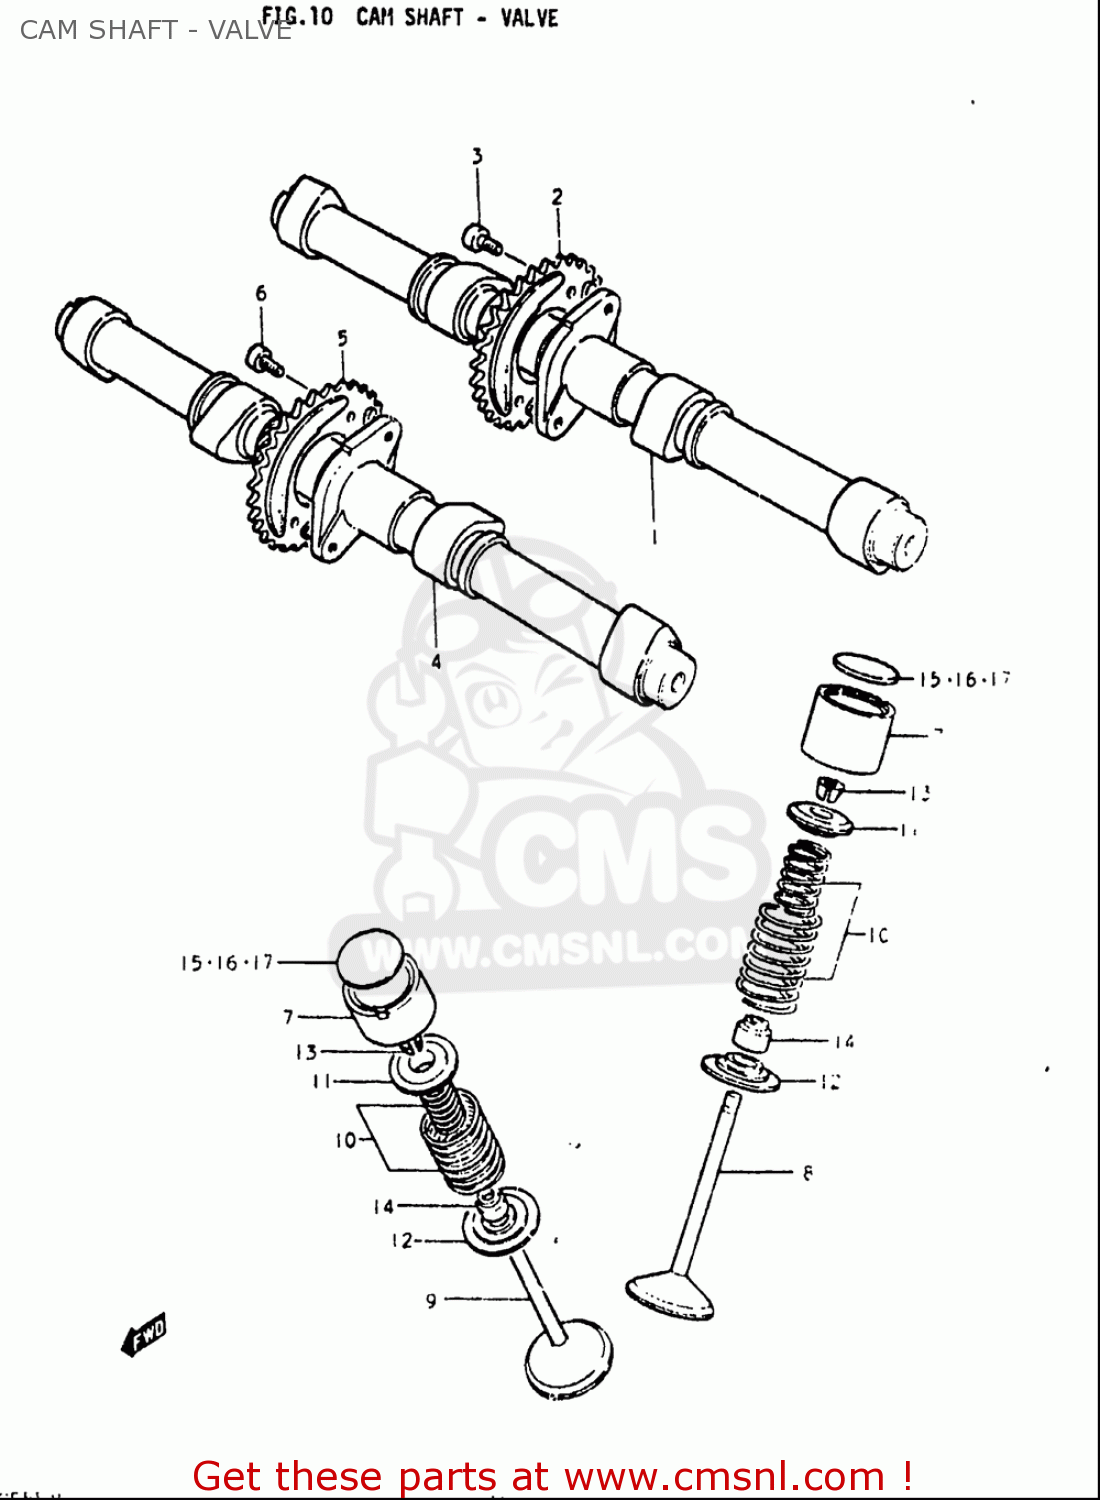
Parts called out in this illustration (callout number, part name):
3	BOLT,VAC.PIPE
6	BOLT,VAC.PIPE
7	TAPPET,INTAKE
8	VALVE,INTAKE
9	VALVE,EXHAUST
10	SPRING SET,VALVE
11	RETAINER,VALVE SPRING
12	SEAT,VALVE SPRING
13	COTTER VALVE
14	SEAL,OIL(7X14.4X9)
15	SHIM,TAPPET(T:2.15)
16	SHIM,TAPPET(T:2.60)
17	SHIM,TAPPET(T:3.05)
18	SHIM SET,TAPPET
19	CASE,SHIM
